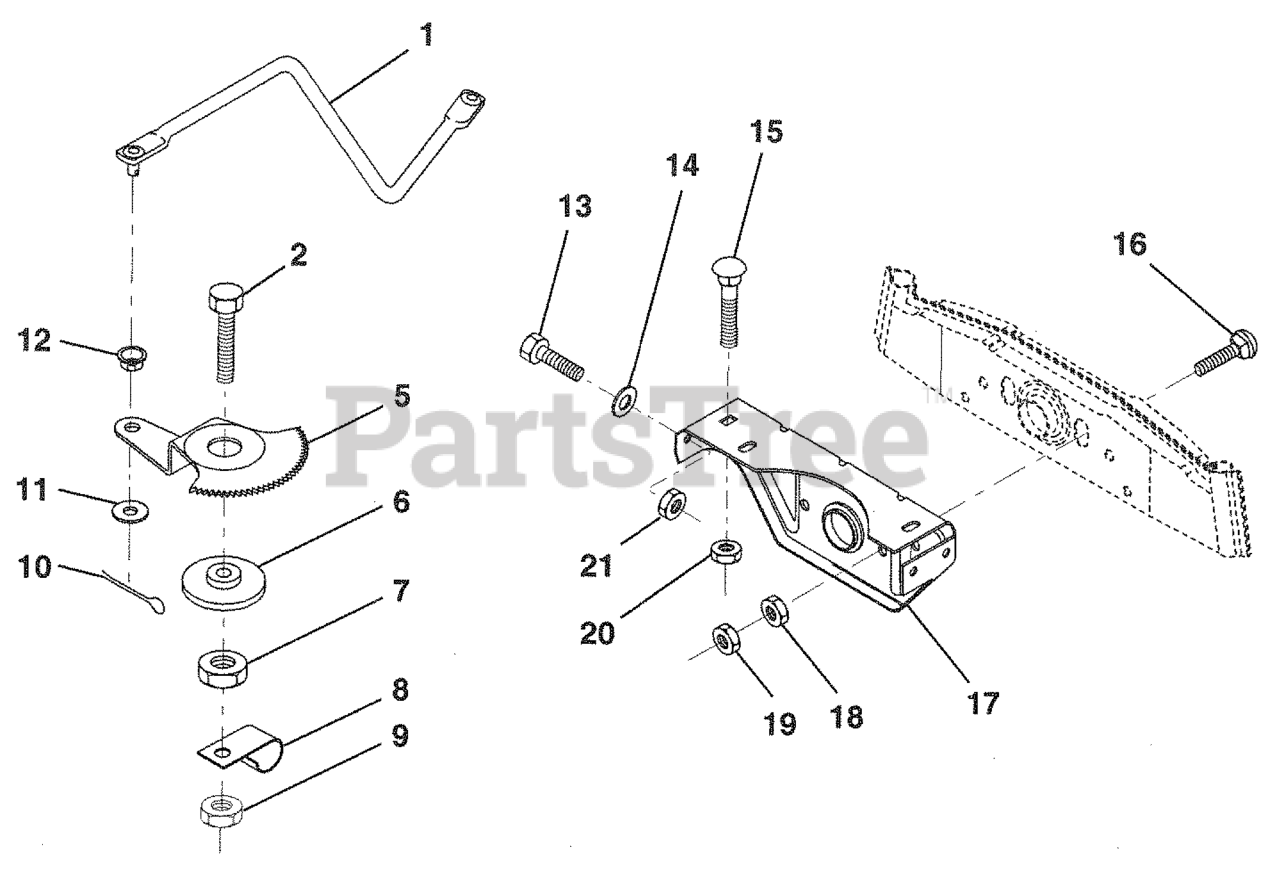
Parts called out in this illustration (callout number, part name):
5	GEAR SECTOR
7	NUT
8	CLIP INSULATOR
9	NUT LTV
10	COTTER PIN
11	WASHER
12	BUSHING.DRAGLINK (2 2)
13	BOLT RB
14	WASHER
15	BOLT
16	BOLT
17	SUPT,FRT AXLE
18	NUT.HEX.3/8-16UNC
19	LOCKNUT
21	LOCKNUT
